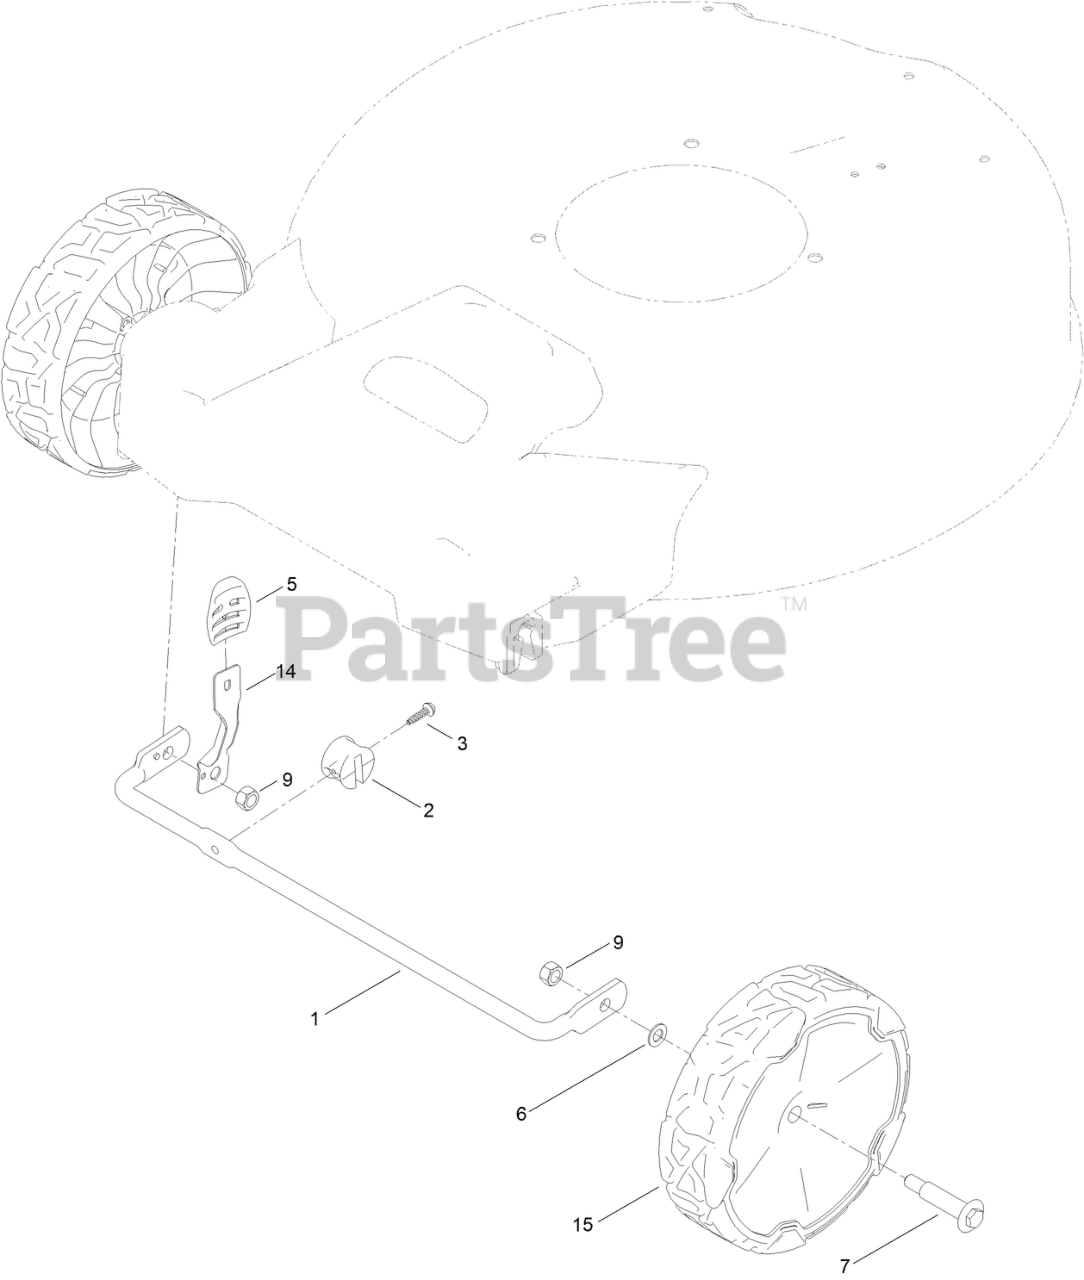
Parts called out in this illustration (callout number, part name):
1	AXLE-FRONT
2	STOP-AXLE
3	SCREW-PLASTIC, HWH
5	KNOB-LEVER, HOC
6	WASHER
7	BOLT-SHOULDER
9	LOCKNUT
14	ARM-SPRING
15	ASM-8" WHEEL, IDLER
